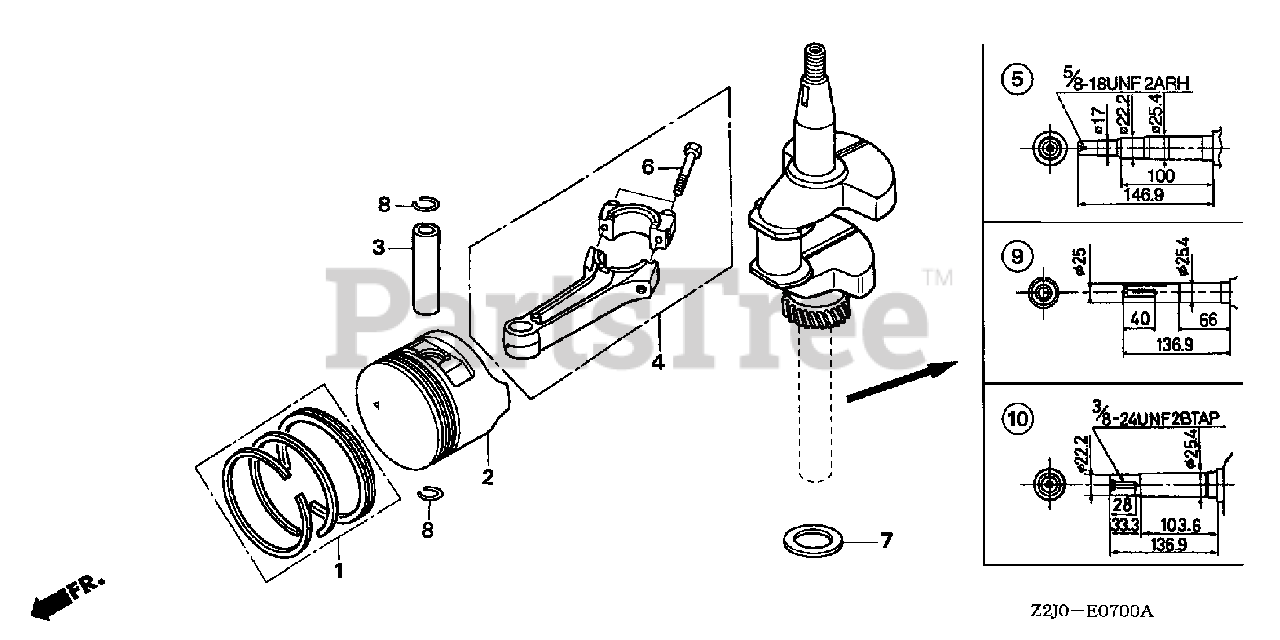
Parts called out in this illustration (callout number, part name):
1	RING SET, PISTON (STD) (TEIKOKU)
1	RING SET, PISTON (STD) (NIPPON)
1	RING SET, PISTON (0.25)
1	RING SET, PISTON (0.50)
1	RING SET, PISTON (0.75)
2	PISTON (STD)
2	PISTON (0.25)
2	PISTON (0.50)
2	PISTON (0.75)
3	PIN, PISTON
4	ROD ASSY., CONNECTING
6	BOLT, CONNECTING ROD
7	WASHER, THRUST (25.6MM)
8	CLIP, PISTON PIN (18MM)
10	CRANKSHAFT
